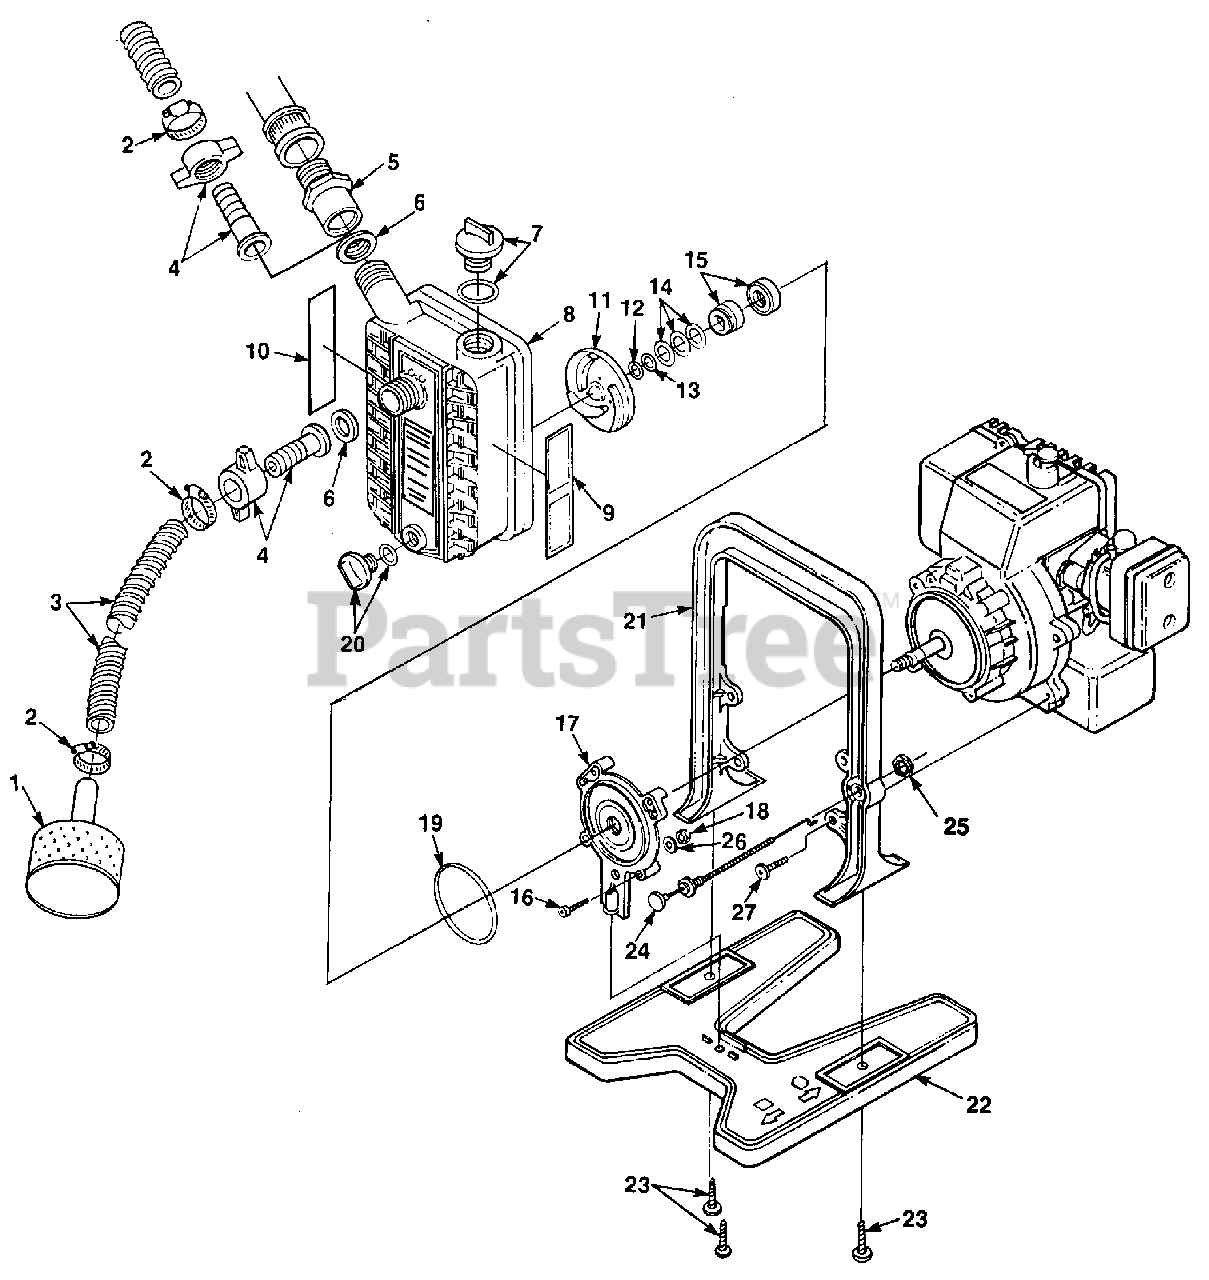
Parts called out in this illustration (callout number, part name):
1	STRAINER (1")
3	HOSE (1")
4	BARBED COUPLING
5	ADAPTOR- Garden Hose
7	CAP w/O-RING
8	PUMP BODY & DECALS
9	DECAL- Operating
10	DECAL- Warning
11	IMPELLER
12	SHIM- (.030) (Impeller)
13	SHIM- (.015) (Impeller)
14	SHIM- (.030) (Seal)
16	SCREW- (10-24 x 7/8")
17	ADAPTOR- (Engine to Pump)
18	NUT- (m5)
19	O-Ring
20	CAP- w/O-Ring
21	HANDLE- Engine mtg.
22	BASE PLATE
23	SCREW- (10-14 x 3/4")
24	THROTTLE
25	NUT-Throttle
27	SCREW- (10-24 x 1.0")
